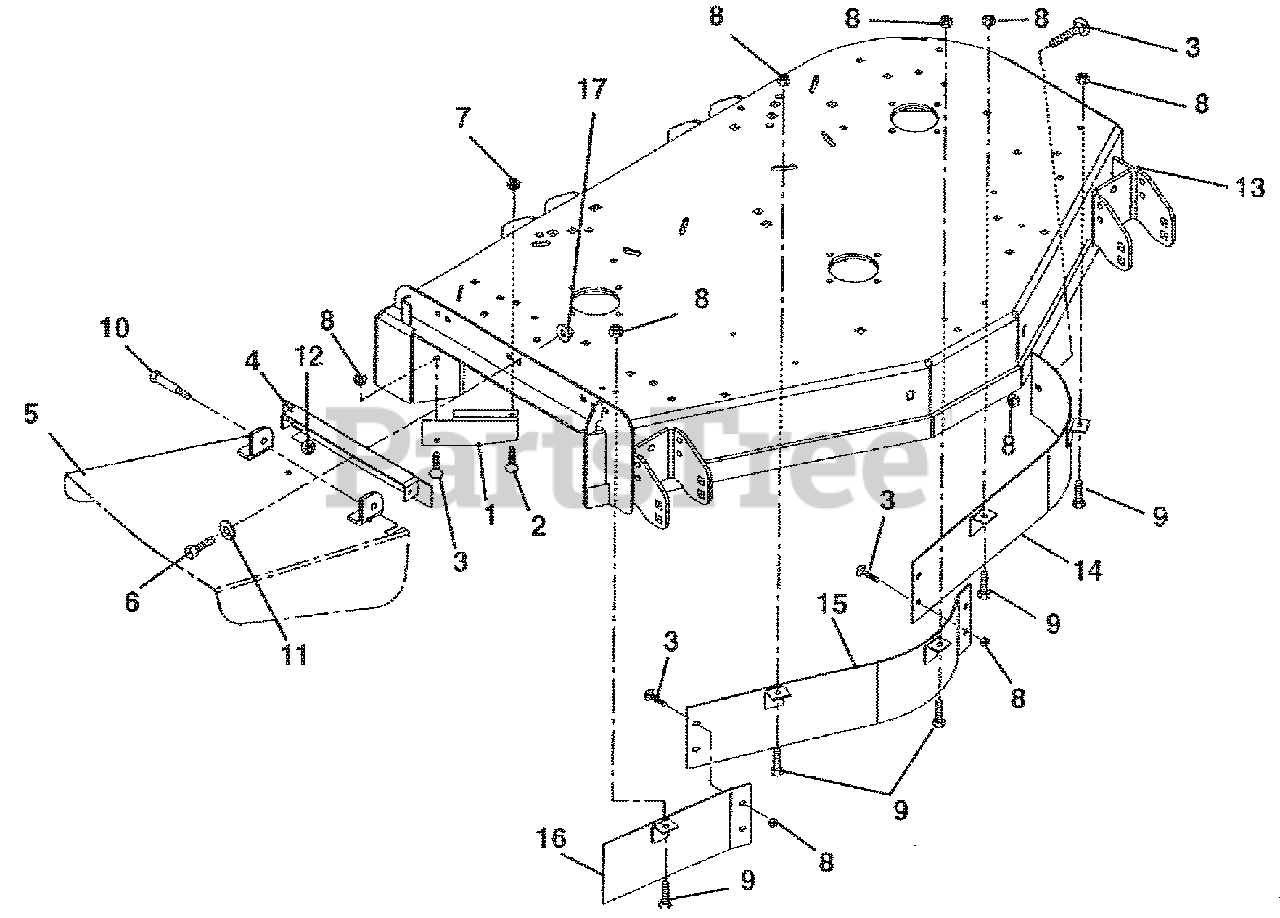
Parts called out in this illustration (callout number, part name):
1	Deflector- 72 in. (070, 072)
2	Bolt-Round Head Square Neck .38-16 x .75 Grade 5
3	Bolt-Round Head Square Neck .31-18 x .75 Grade 5
4	Weldment, Discharge Chute Bracket (066, 071)
5	Chute-Discharge (066)
6	Bolt-Hex .38-16 x 1.00 Grade 5
7	Nut-Locking-Top-Flange .38-16
8	Nut-Locking-Top-Flange .31-18
9	Bolt, Hex .31-18 x .75 Grade 5
10	Bolt, Shoulder .38-16 x .50 Socket Head
11	Washer, Flat Steel .38 x .875 x .083 (066, 071)
12	Nut, Locking-Center .38-16
13	Weldment, 52 in. Mower Deck (066, 071)
14	Weldment, Upper Baffle Left 52 in. (066, 067)
15	Weldment, Baffle, Center Front 52 in. (066, 071)
16	Weldment, Baffle, Right Front 52 in. (066, 071)
17	Nut, Flange 0375-16
